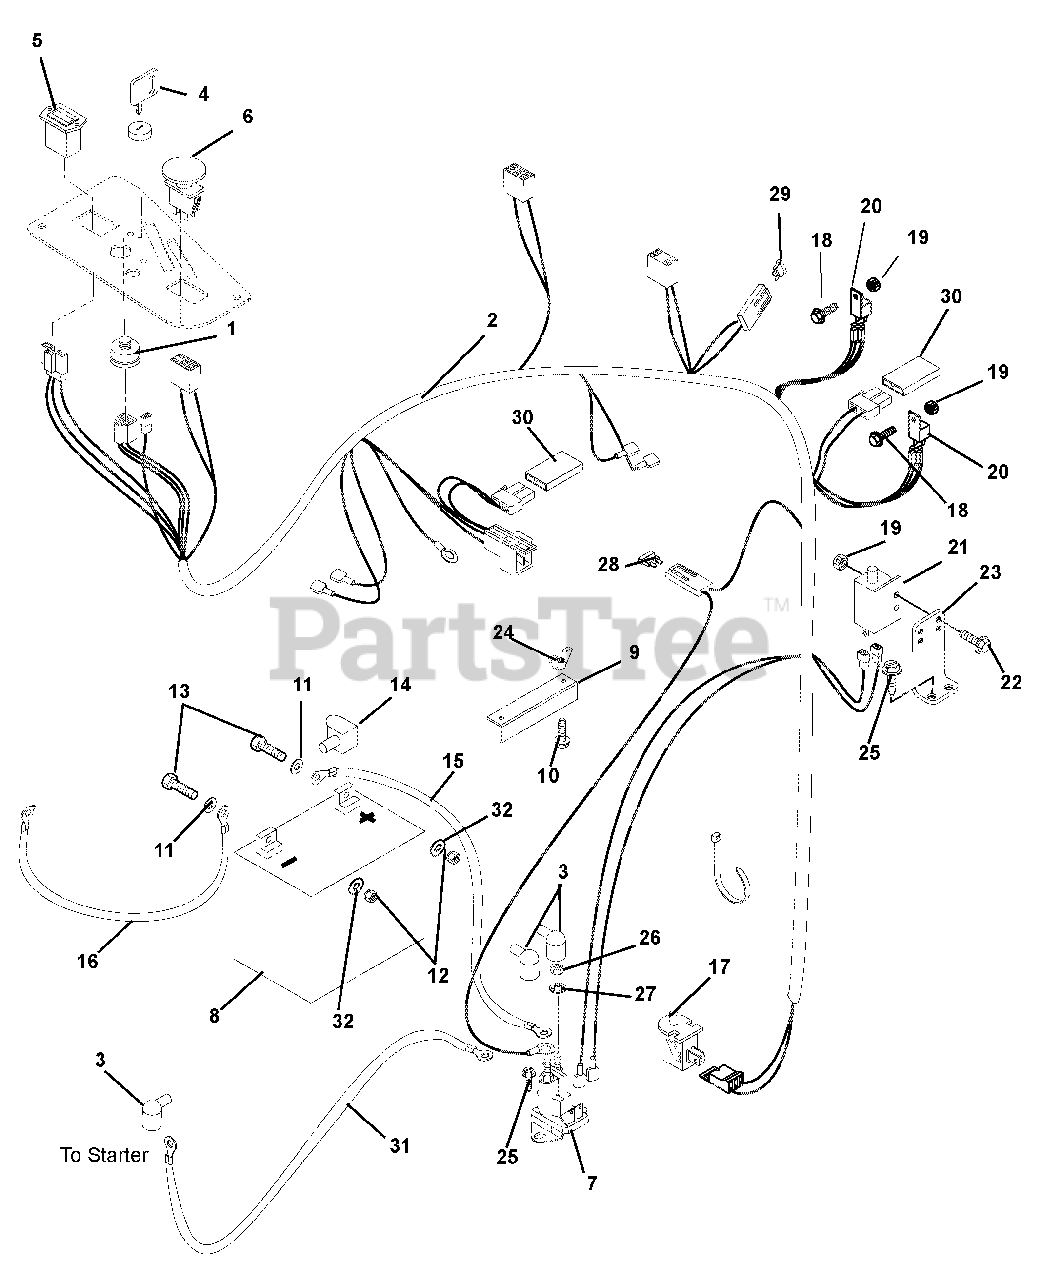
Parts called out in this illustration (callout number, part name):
1	SWITCH, IGNITION
2	HARNESS - CZ EYE-Q REMOTE SOL.
3	BOOT, EYELET TERMINAL
4	KEY, W/ SHIELD
5	HOURMETER-QUARTZ 80VDCMAX
6	SWITCH, CLUTCH
7	SOLENOID
8	BATTERY, 300 CCA 10U1L
9	HOLD DOWN
10	BLT-RDHDSQNK .25-20X7.50 GR2YZ
11	@WSHR-FL-STL.281X.62X.065 YWZC
12	@NUT-HEX .25-20 YWZC
13	@BLT-HEX .25-20X.75 GR5 YWZC
14	INSULATOR
15	CABLE-POSITIVE BATTERY 9.00"
16	CABLE-NEGATIVE BATTERY 24.00"
17	SWITCH- SNAP MTG N.O.
18	@SCR-MCH 10-24X.50 HWH YWZC
19	@NUT-LK-NYL 10-24 W/INSRT YWZC
20	RELAY
21	SWITCH- SINGLE POLE N.O.
22	@SCR-MCH 10-24X.75 HWH YWZC
23	BRAKE SWITCH MOUNT - BLACK
24	NUT-LK WING .250-20 YWZC
25	@SCR-TAP .25-20X.50 HWH TR YWZ
26	NUT-JAM .31-24 YWZC
27	@WSHR-LK .31X.078 REG YWZC
28	FUSE-25 AMP ATC TYPE
29	FUSE 20AMP
30	DIODE, CONNECTOR SHELL
31	CABLE, STARTER .31X23.00X.31
32	@WSHR-LK .25X.062 REG YWZC
